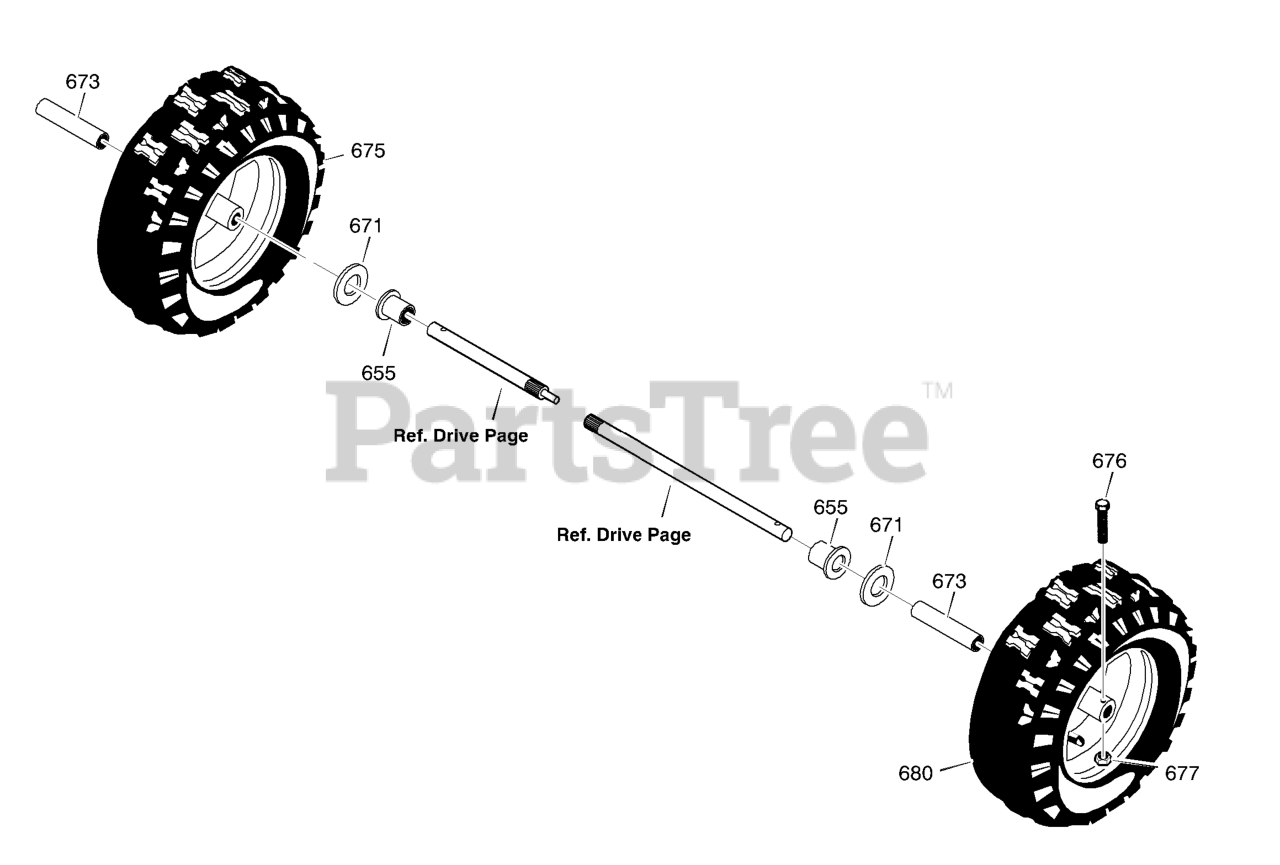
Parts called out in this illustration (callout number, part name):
655	BEARING, AXLE
671	FLATWASHER
673	BUSHING, WHEEL
675	TIRE & RIM, LEFT
676	SCREW, 1/4-20X1.75 HH
677	NUT, 1/4-20 HEX NYLOCK
680	TIRE & RIM, RIGHT
